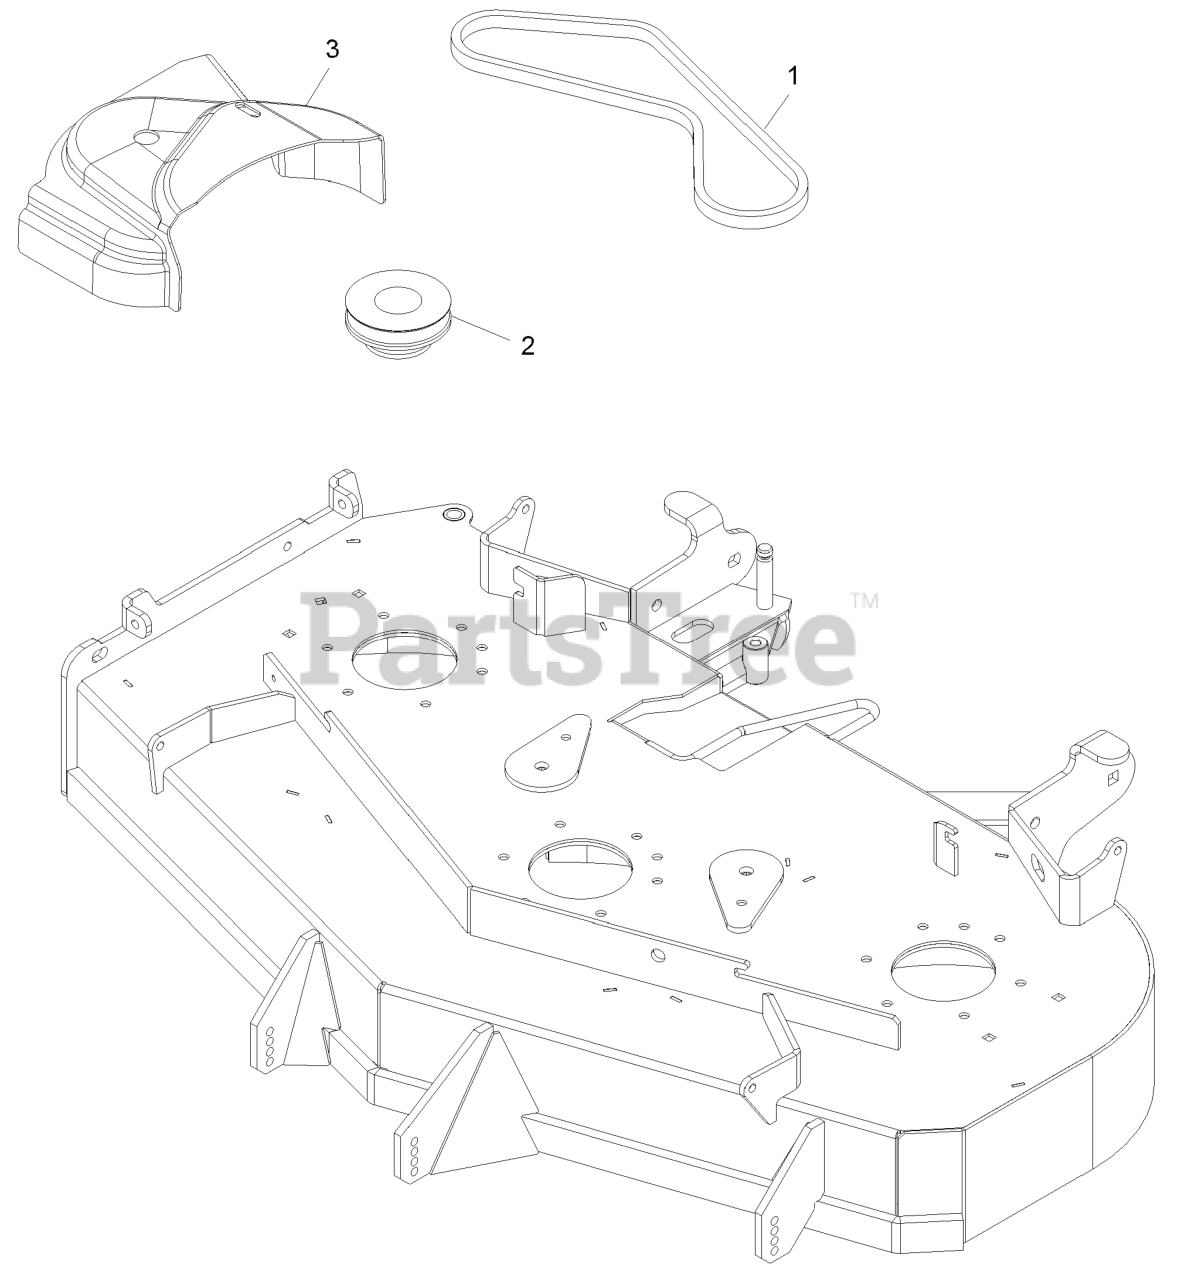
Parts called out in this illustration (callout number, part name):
1	Belt, Blower (48")
2	Blade, Extreme 72
3	Cover,Belt Uv 48
